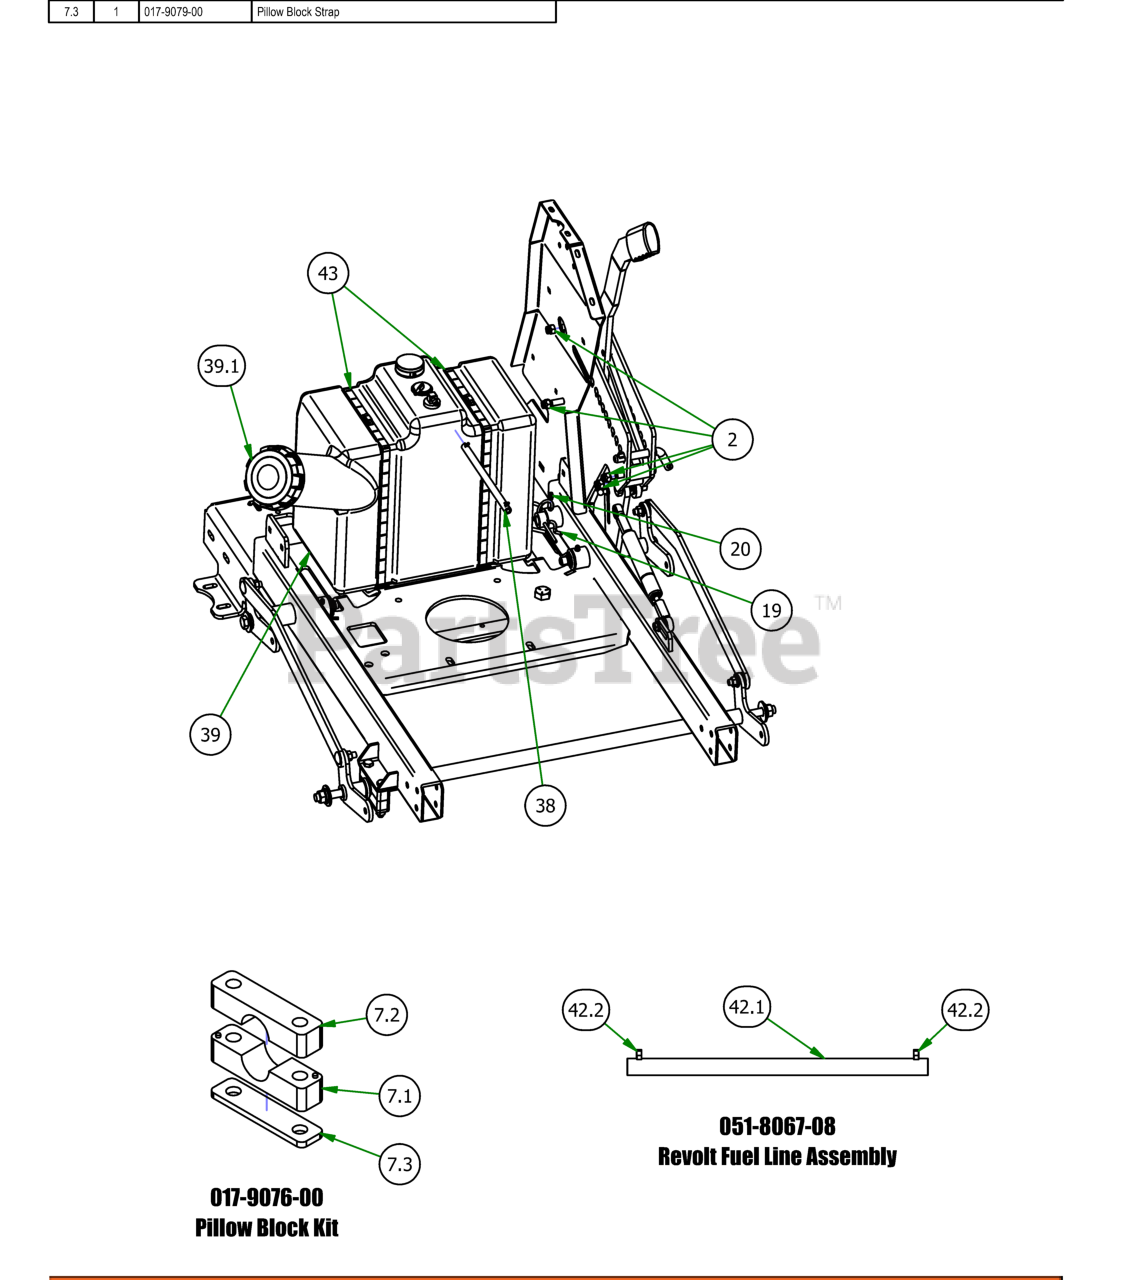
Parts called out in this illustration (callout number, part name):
2	3/8-16 NYLON INSERT LOCKNUT ZINC
7.1	Pillow Block MZ male
7.2	Pillow Block MZ female
7.3	Pillow Block Strap
19	Revolt Cotter Pin for 7/8" to 1" shank
20	1/4" Press in Grease Fitting
38	Revolt Fuel Line Assembly
39	2019 REVOLT FUEL TANK
42.1	1/4 Fuel Line
42.2	1/4 Fuel Hose Clamp
43	2019 Stand On Gas Tank Strap
